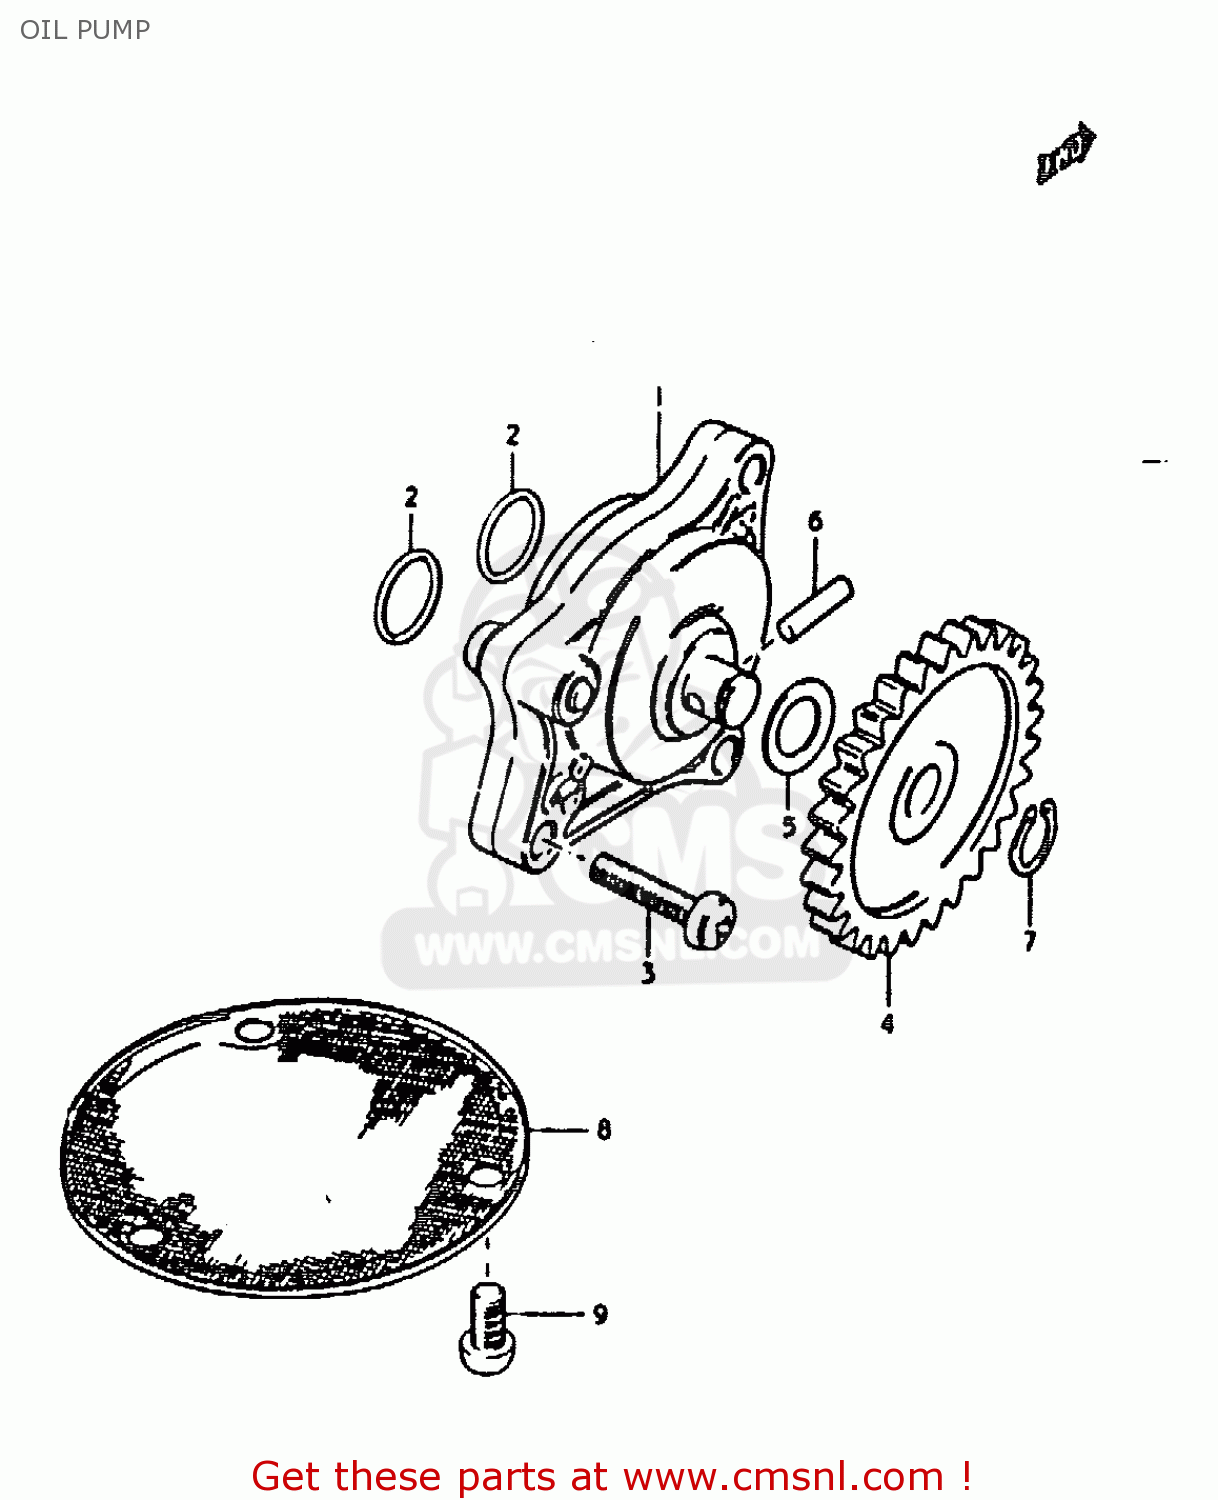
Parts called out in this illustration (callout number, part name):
1	PUMP ASSEMBLY,OIL
2	O RING(D:1.9,ID:13)
3	SCREW
4	GEAR,OIL PUMP DRIVEN
5	SHIM
6	PIN(4X15.8)
7	CIRCLIP
8	STRAINER,ENGINE OIL
9	SCREW 6X12
